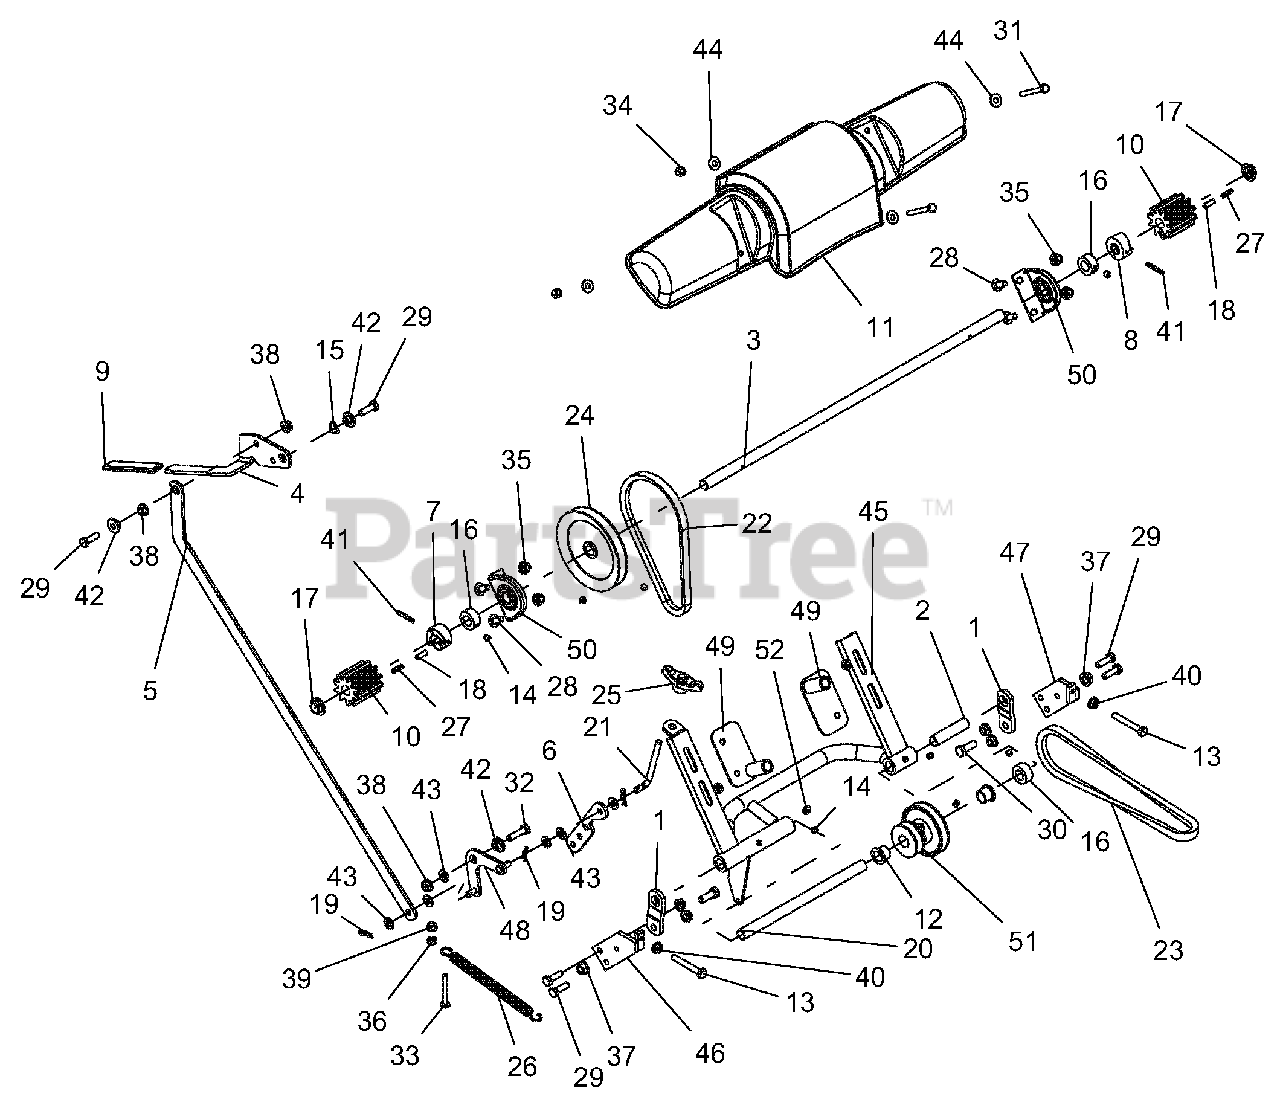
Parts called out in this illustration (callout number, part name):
1	BRKT, SP FRAME PIVOT (BLACK)
2	SHAFT, PIVOT SHORT
3	SHAFT, WHEEL DRIVE
4	LEVER, SP ENGAGEMENT (BLACK)
5	BAR, ENGAGEMENT LEVER CONN. (BLACK)
6	BRKT, ENGAGE, ADJ (BLACK)
7	CLUTCH, RIGHT SP
8	CLUTCH, LEFT SP
9	GRIP, MZR/MOMENT SP 7/8X3/4X4
10	GEAR, DRIVE (SP)
11	COVER, PLASTIC -SP (HIGH WHEEL)
12	BUSHING, FLANGED .75X.625X.62
13	HHCS 5/16-18 X 2-1/4 FULL THD
14	SET SCREW 5/16-18 X 5/16 CP
15	WSHR, WAVE .50X.75X.015 .13FRHT
16	SET COLLAR .625ID X .50
17	NUT, PUSH .625 DIA.LPA
18	DOWEL PIN 1/4 X 3/4
19	PIN-HAIR, ENDRIES #25 YWZC
20	SHAFT, PIVOT LONG
21	THDED ROD .31-18X3.0THD YZ
22	V-BELT, 4L-RAW EDGE
23	V-BELT, 4L-RAW EDGE
24	PULLEY, 5" OD X 5/8" ID
25	KNOB, WING .31-18 UNC NYL/TALC
26	SPRG, EXTENSION
27	SPRG, COMPRESSION
28	BLT-RHDSSQNK .31-18X.75 G5YZ
29	BLT-HEX .31-18X1.00 GR5 YWZC
30	BLT-HEX .38-16X1.00 GR5 YWZC
31	BLT-HEX .25-20X2.25 GR5 YWZC
32	BLT-HEX .31-18X1.25 GR5 YWZC
33	BLT-HEX .25-20X2.00 GR5 YWZC
34	NUT-LK-NYL .250-20 YWZC
35	NUT-LK-NYL-FLG .31-18 YWZC
36	NUT-HEX .25-20 YWZC
37	NUT, LK-TOP-FLG .38-16 YWZC
38	NUT, LK-TOP-FLG .312-18 YWZC
39	NUT, LK-TOP-FLG .25-20 YWZC
40	@NUT-SPNLK-FLG .312-18 YWZC
41	PIN-ROLL .188X1.25
42	BSHG, FLG .32X.500.344X.880
43	WSHR-FL-STL.344X.688X.065YWZC
44	WSHR-FL-STL.312X.734X.065 YWZ
45	WMT-SELF PROPEL FRAME (BLACK)
46	WMT-PIVOT, RH SP FRAME (BLACK)
47	WMT-PIVOT, LH SP FRAME (B)LACK
48	WLDMT, BELL CRANK (BLACK)
49	WLDMT, SP BELT COVER MOUNTING (BLACK)
50	BEARING ASSY, SP TOPSHAFT, HWM
51	WMT,DBL SP IVP PULLEY 17344K
52	GREASE, FITTING 5/16 DRIVE IN
